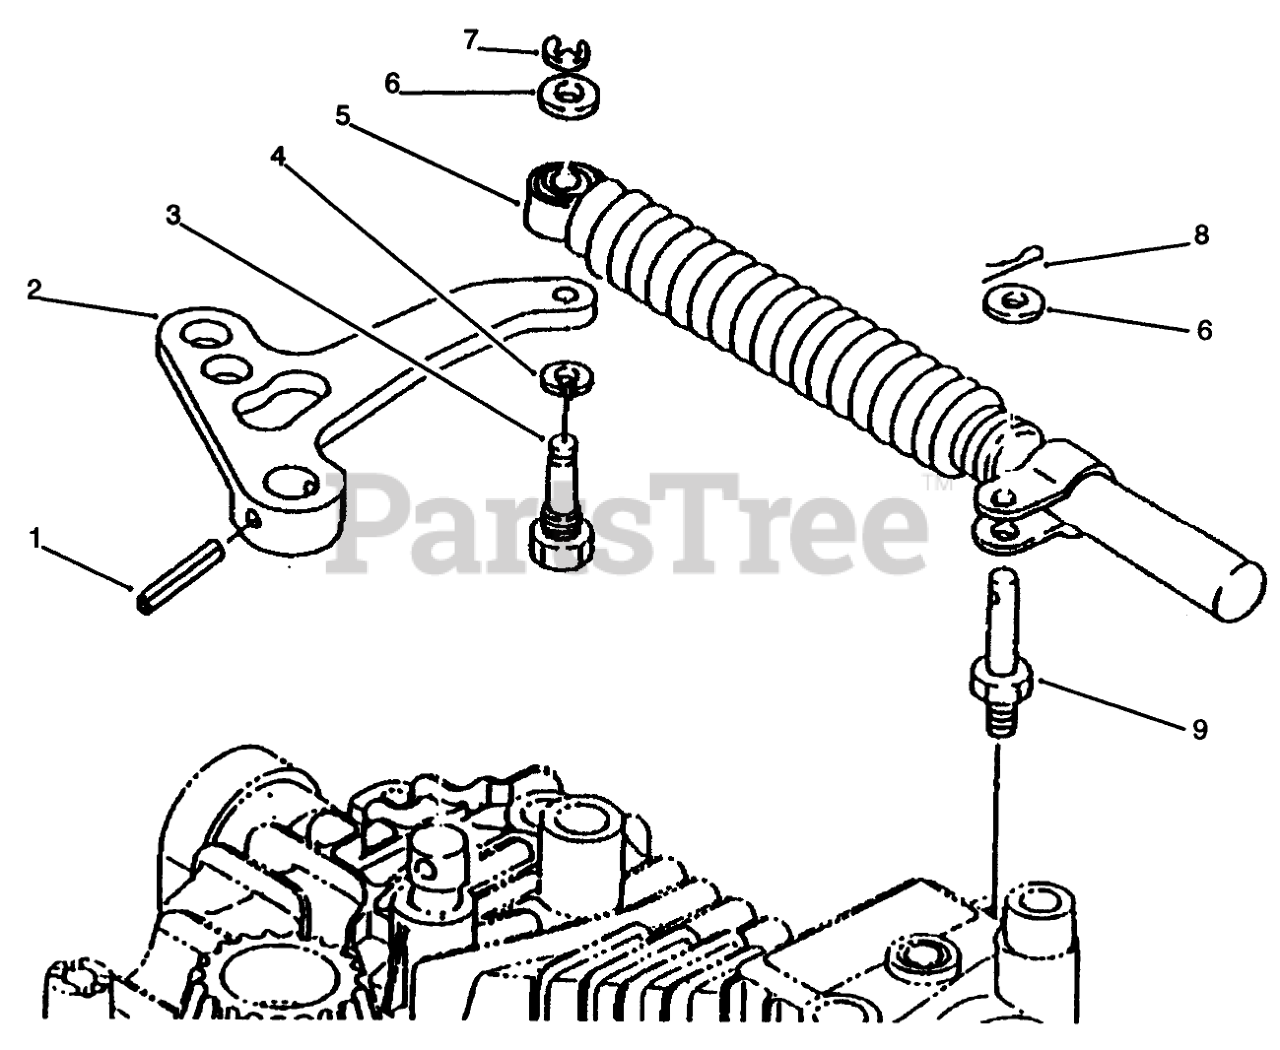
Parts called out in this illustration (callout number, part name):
1	PIN-ROLL
4	WASHER
5	ABSORBER - SHOCK
6	WASHER
8	PIN-COTTER
